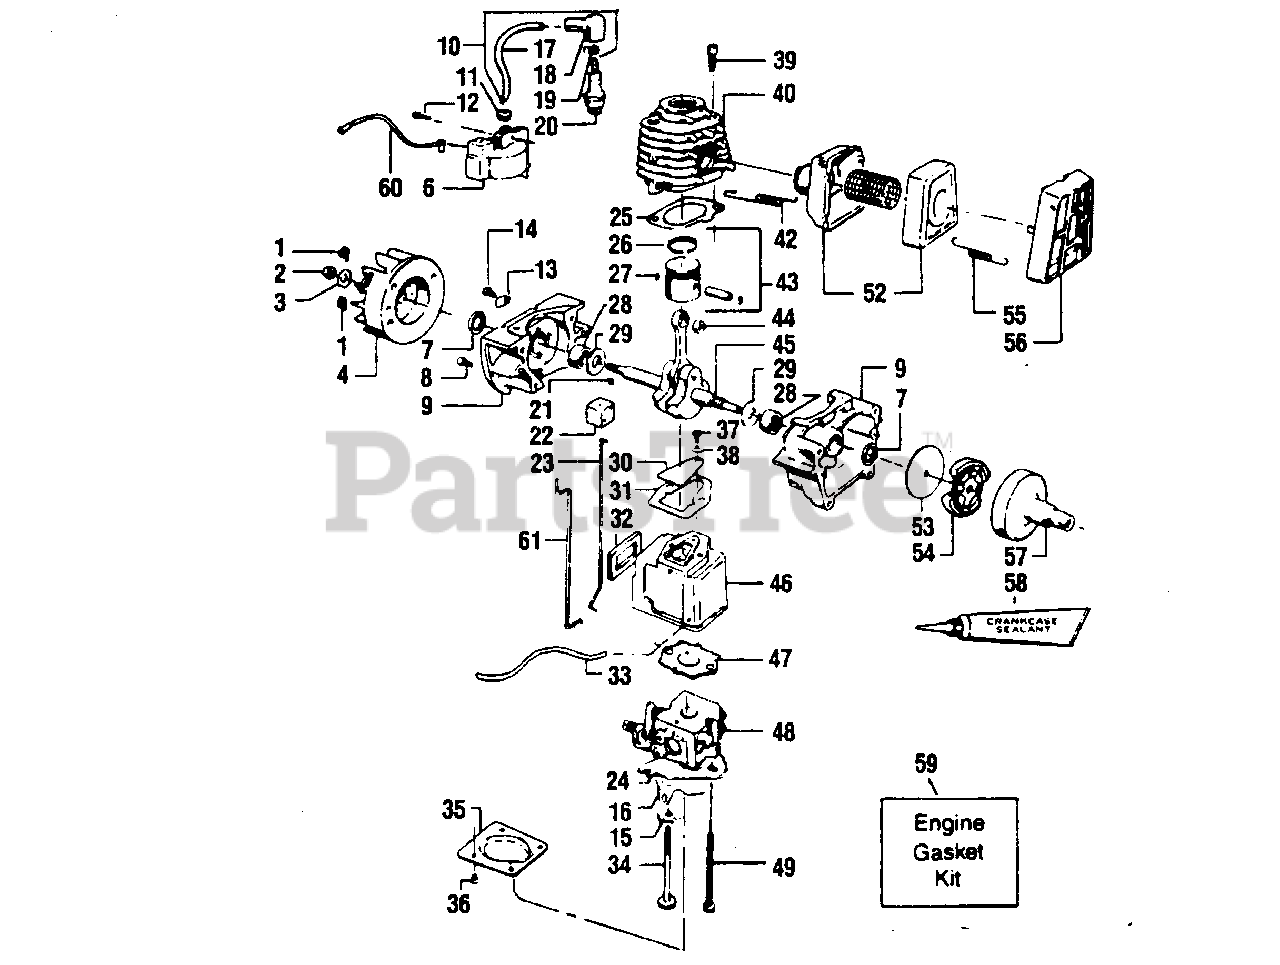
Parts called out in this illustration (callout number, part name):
1	Starter Dog Spring
2	Flywheel-Nut
3	Flywheel Washer
4	Flywheel Assembly (incl.#1)
6	Ignition Module Kit
7	Crankcase Seal
8	Screw-Crankcase
9	Crankcase Assembly (Incl. #7, 28 & Qty. 4 of #8)
10	High Tension-Load Assembly (Incl. #17, 18 & 19)
11	Grommet-Plug Wire
12	Screw #8-32x3/4". Fil. Hd.-Ignition Module
13	Choke Wire Clamp
16	Choke Shutter
17	High Tension Lead Wire
18	Spark Plug Boot
19	Spark Plug Lead Connector
20	Spark Plug (RCJ-8)
21	Key-Flywheel
22	Boot-Throttle Choke Wire
23	Throttle Wire (Red)
24	Guide Plate
25	Cylinder Gasket
26	Ring-Piston
27	Retainer-Wrist Pin
28	Bearing-Crankcase
29	Washer-Thrust-Crankcase
30	Reed Valve
31	Gasket-Carburetor Case to Crankcase
32	Seal-Carburetor Case to Line Kit
33	Line Kit
35	Cover-Carburetor Case
36	Screw-#6-18x9/16" Carburetor Case Cover
37	Screw-#5-19x5/16" Pan Hd. Reed Valve
38	Washer-Reed Valve Screw
39	Screw-# 14-20x3/4" Hex Socket Hd. Cylinder
40	Cylinder
42	Spring Muffler A tachment
43	Piston Kit (Inc.26,27,Pin)
44	Bearing-Wrist Pin
45	Crankshaft & Rod Assemby (Inc.44)
46	Carburetor Housing
47	Gasket-Carburetor
48	Carburetor
49	Screw-# 10-24x1-7/8" Fil. Hd. Carburetor
52	Muffler Ass'y.
53	Kit-Clutch Washer
54	Kit-Clutch Assembly (Incl. Washer)
55	Spring-Muffler Guard
56	Guard-Muffler
57	Coupling & Bearing Assembly
58	Sealent-Crankcase (Not Supplied with Unit)
59	Kit-Engine Gasket
60	Lead Wire Switch
61	Choke Wire
